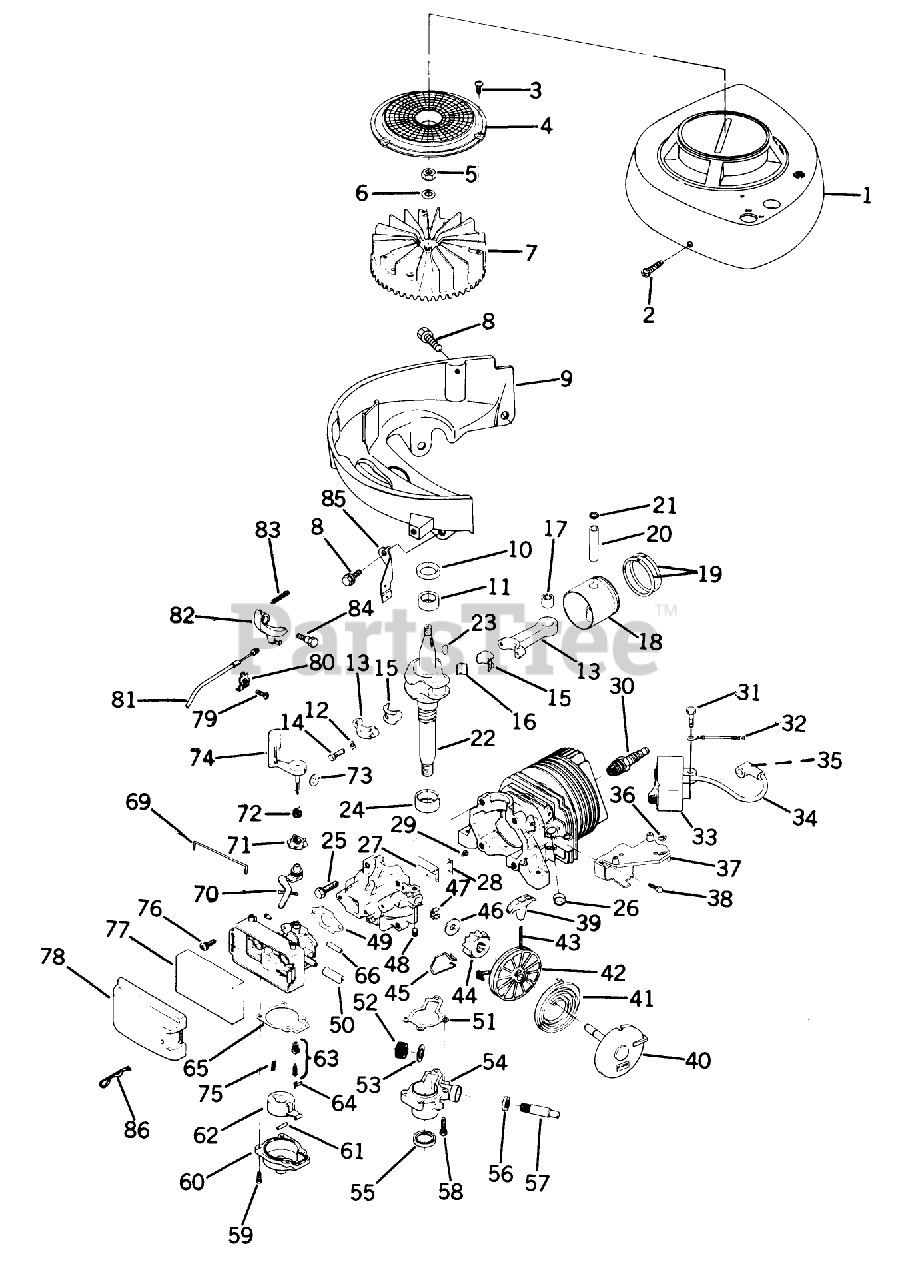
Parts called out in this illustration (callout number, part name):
2	SCREW F
3	SCREW F
4	Screen-Flywheel
5	NUT
8	SCREW-SEMS
14	SCREW
15	LINER ASM
17	BEARING AY F
21	RING-RETAINING
23	KEY
24	BEARING S
25	SCREW S
26	PLUG-CORE VF
28	PLATE-BACKUP, REED
34	HT LEAD&COVER XEV
36	NUT-CLIP
37	BRACKET S
39	HANDLE STARTER S
41	SPRING S
45	SPRING F
46	WASHER S
48	SET SCREW
49	GASKET CARB S
51	GASKET S
52	GEAR, DR SHAFT S
53	THRUST WASHER
56	SEAL S
59	SCREW-HH
66	TUBING PRIMER S
68	F-SCREW CARB
69	RETAINER
70	LEVER
71	ADJUSTMENT COLLAR
72	SPRING
73	DISC S
76	SCREW
80	CLIP S
82	LEVER LOCKOUT S
84	BOLT S
86	HAIR PIN
